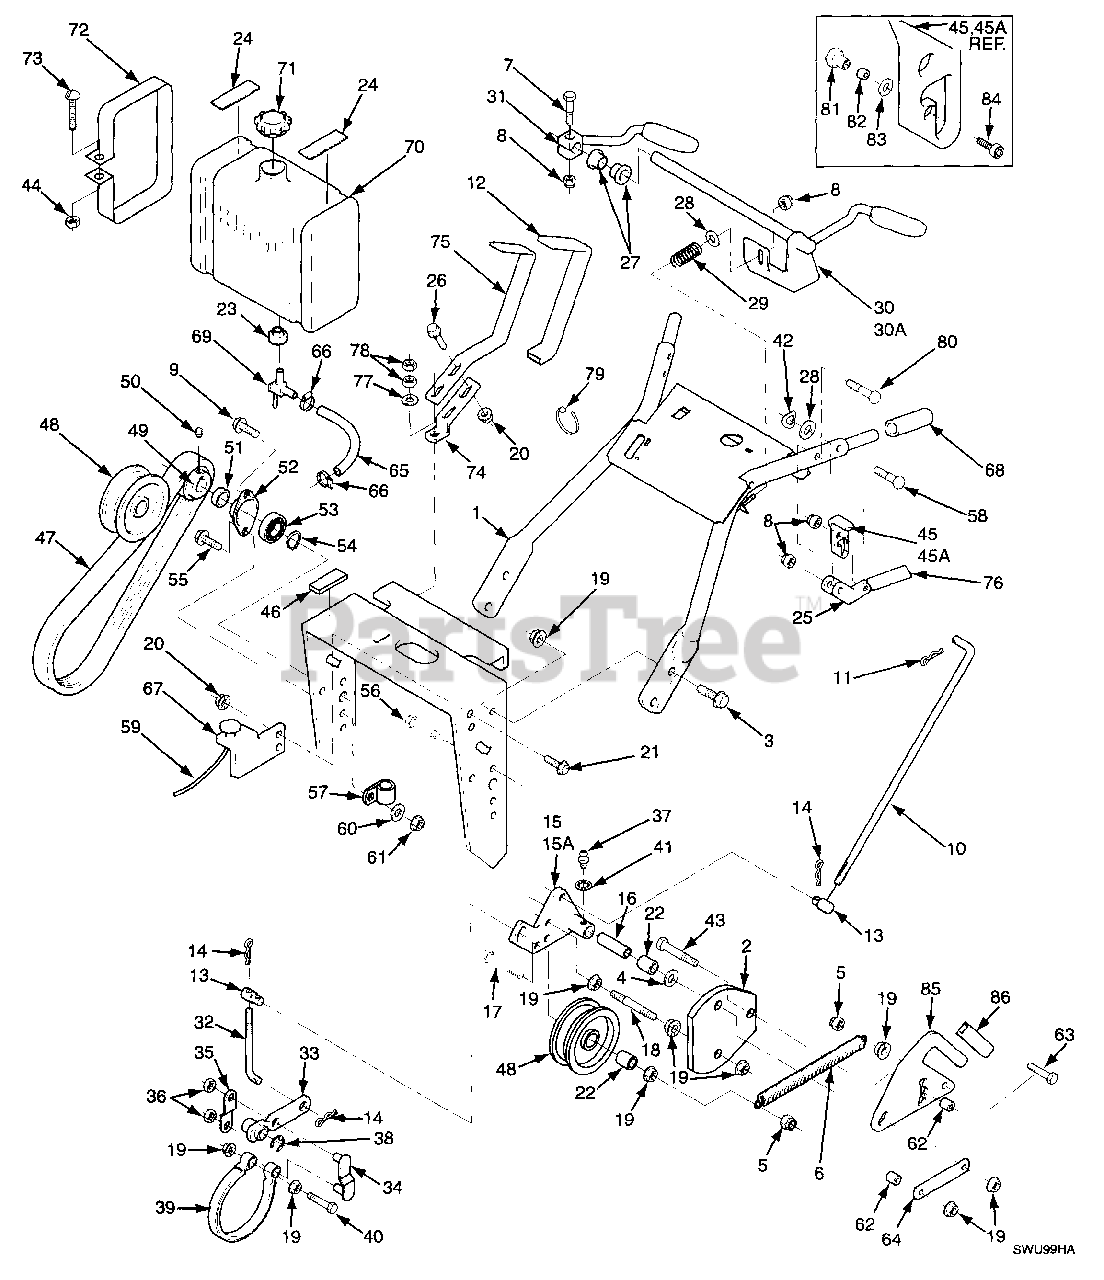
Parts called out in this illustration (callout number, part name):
1	Handle Assembly 16" Frame
2	Belt Guard
3	Capscrew, 3/8-16 x 1" Ser. Flange
4	Flatwasher, 3/8 (.391 x .938 x .105)
5	Nut, 3/8-16 Elastic Stop
6	Spring, Idler
7	Bolt, 5/16-18 x 1-1/4" Hex Head
8	Nut, 5/16-18 Elastic Stop
9	Capscrew, 1/4-20 x 3/4" Hex Head
10	Control Rod, Steering
11	Hair Pin, Small
12	Grip, Shift Lever
13	Swivel Joint
14	Hair Pin, Large .094 Diameter
15	Idler Bracket, RH
15A	Idler Bracket, LH
16	Idler Sleeve
17	Bolt, 3/8-16 x 3/4" Hex Head
18	Support Belt Guard
19	Nut, 3/8-16 Serrated Flange
20	Nut, 5/16-18 Serrated Flange
21	Cpscrw, 5/16-18 x .75" Ser. Flng.
22	Spacer
23	Bushing, Fuel Tank
24	Rubber Pad, (Upper)
25	Steering Lever
26	Capscrew, 5/16-18 x 1" Ser. Flng.
27	Bushing, Operator Presence
28	Washer, 5/16 (.375 x .875 x .083)
29	Spring, Operator Presence
30	Operator Presence Lever, LH (Small Frame)
31	Operator Presence Lever, RH
32	Brake Rod
33	Brake Lever
34	Brake Link
35	Brake Link Plate
36	Nut, 3/8 Push-on
37	Greese Fitting, Straight 1/4-28
38	Retaining Ring, 5/8 Ext. "E"
39	Brake Band
40	Bolt, 3/8-16 x 2" Hex Head
41	1/4" Internal Tooth Lockwasher
42	Curved Spring Washer
43	Bolt, Hex Head 3/8-16 x 1.25"
44	Nut, 1/4-20 Hex
45	Neutral Latch, RH
45A	Neutral Latch, LH
46	Rubber Pad (Lower)
47	Belt, Wheel Drive
48	Idler Pulley, Wheel Drive
49	Pulley, Jackshaft
50	Setscrew, Hex Socket Knurl Cup Pt. 5/16-18 (nylock)
51	Spacer, Jackshaft Pulley
52	Flange, Jackshaft Bearing
53	Bearing, Jackshaft
54	Retaining Ring, 5/8 Ext. Basic
55	Capscrew, 1/4-20 x 1" Ser. Flange
56	Bolt, 3/8-16 x 3.25"
58	Bolt, 5/16-18 x 2" Hex Head
59	Choke Control
60	Flatwasher, 5/16 (.375 x .875 x .083)
61	Nut, 1/4-20 Elastic Stop
62	Spacer
63	Bolt, Hex Head 3/8-16 x 1.25"
65	Fuel Hose,1/4" ID, 10" (KH Only)
66	Clamp, Fuel Hose
67	Bracket, Choke Mounting
68	Grip, Handle
69	Valve, Fuel Shut Off
70	Fuel Tank Assy.
71	Fuel Tank Cap
72	Strap, Fuel Tank
73	Screw, 1/4-20 x 2" Rnd Hd Slotted
74	Shift Lever
75	Shift Lever
76	Grip, Steering Lever
77	Washer, 3/8 (.391 x .938 x .105)
78	Nut, 3/8-24 UNF
79	Cable Tie
80	Bolt, 5/16-18 x 2-1/2"
81	Bushing, Bearing Retainer
82	Bearing
83	Washer, #8-.170 x .375 x .032
84	Capscrew, Socket Head #8-32 x .50"
85	Lever, Traction Adjustment
86	Grip, Traction Adjustment Lever
